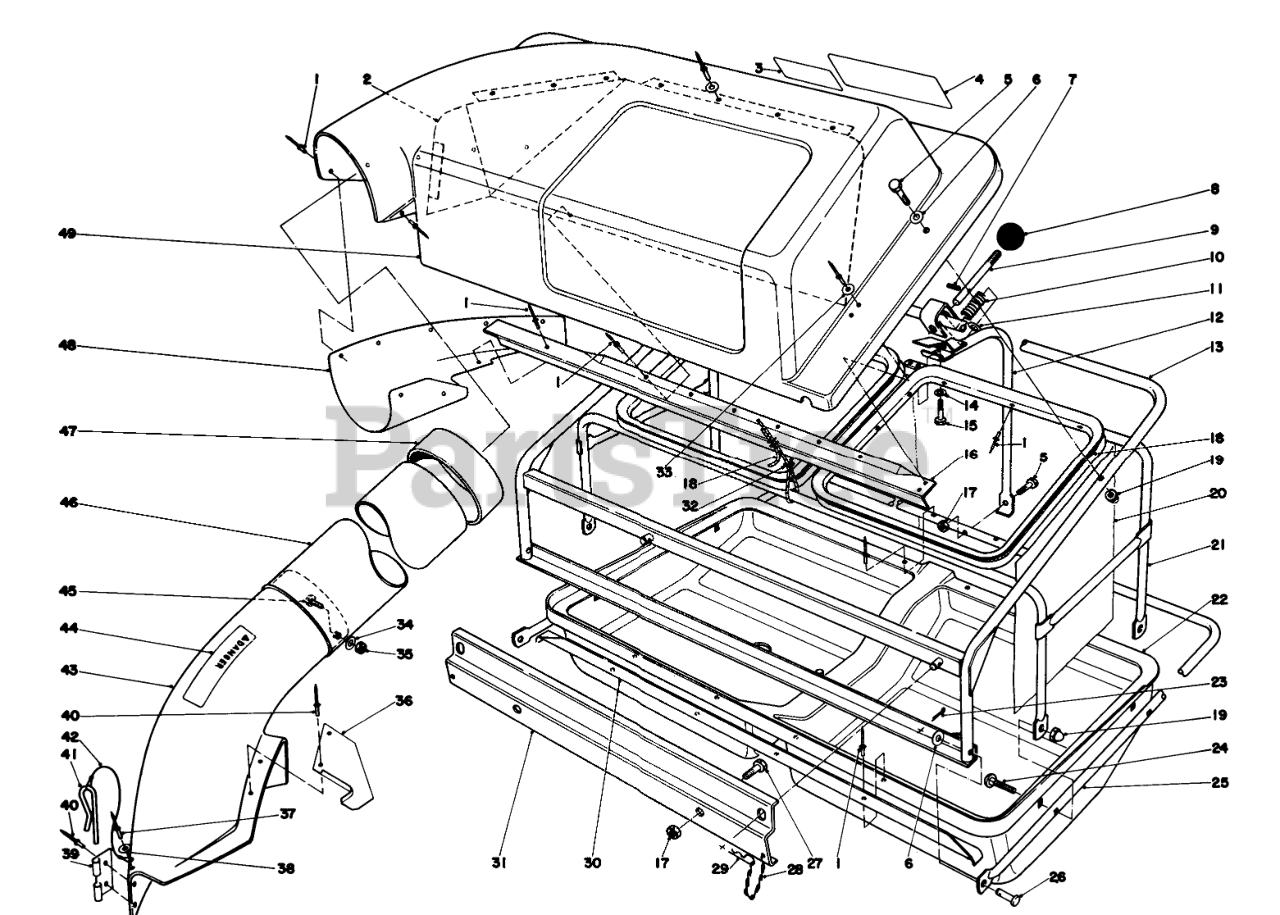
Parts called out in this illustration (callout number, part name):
2	Screen Cover
3	LATCH DECAL
4	EASY FILL DECAL
5	SCREW-HH
6	WASHER-PLAIN
7	PIN-ROLL, SLOT
9	Lever-Latch
10	Compression Spring
11	WASHER-FLAT
12	Handle Assembly
13	Frame Assembly
14	WASHER-LOCK
15	SCREW-HH
16	Bracket Screen Support
17	NUT-LOCK, CONE
18	RETAINER CORD
19	NUT-LOCK, CAP
20	Curtain
21	Bag Support Assembly
22	Hopper
23	PIN-COTTER
24	SCREW-CARR
25	HOPPER SUPT TUBE B
26	CLEVIS
27	SCREW-HH
28	6-LINK CHAIN W/HOOK
29	PIN-HAIR
30	HOPPER SUPT STRAPB
31	Bracket Frame Support
32	COUPLER
33	WASHER-FLAT
34	WASHER-FLAT
35	NUT-KEPS
36	CHUTE SUPT BRKT
37	RIVET-BLIND
38	WASHER-PLAIN
39	BRACKET-MOUNTING, CHUTE
40	RIVET-BLIND
41	PIN-LOCKING, CHUTE
42	LANYARD
43	Chute Assembly (Incl. Ref. #36-44)
44	Decal-Chute
45	BOLT-CARR
46	Duct
47	DUCT SEAL
48	Deflector
49	Cover
